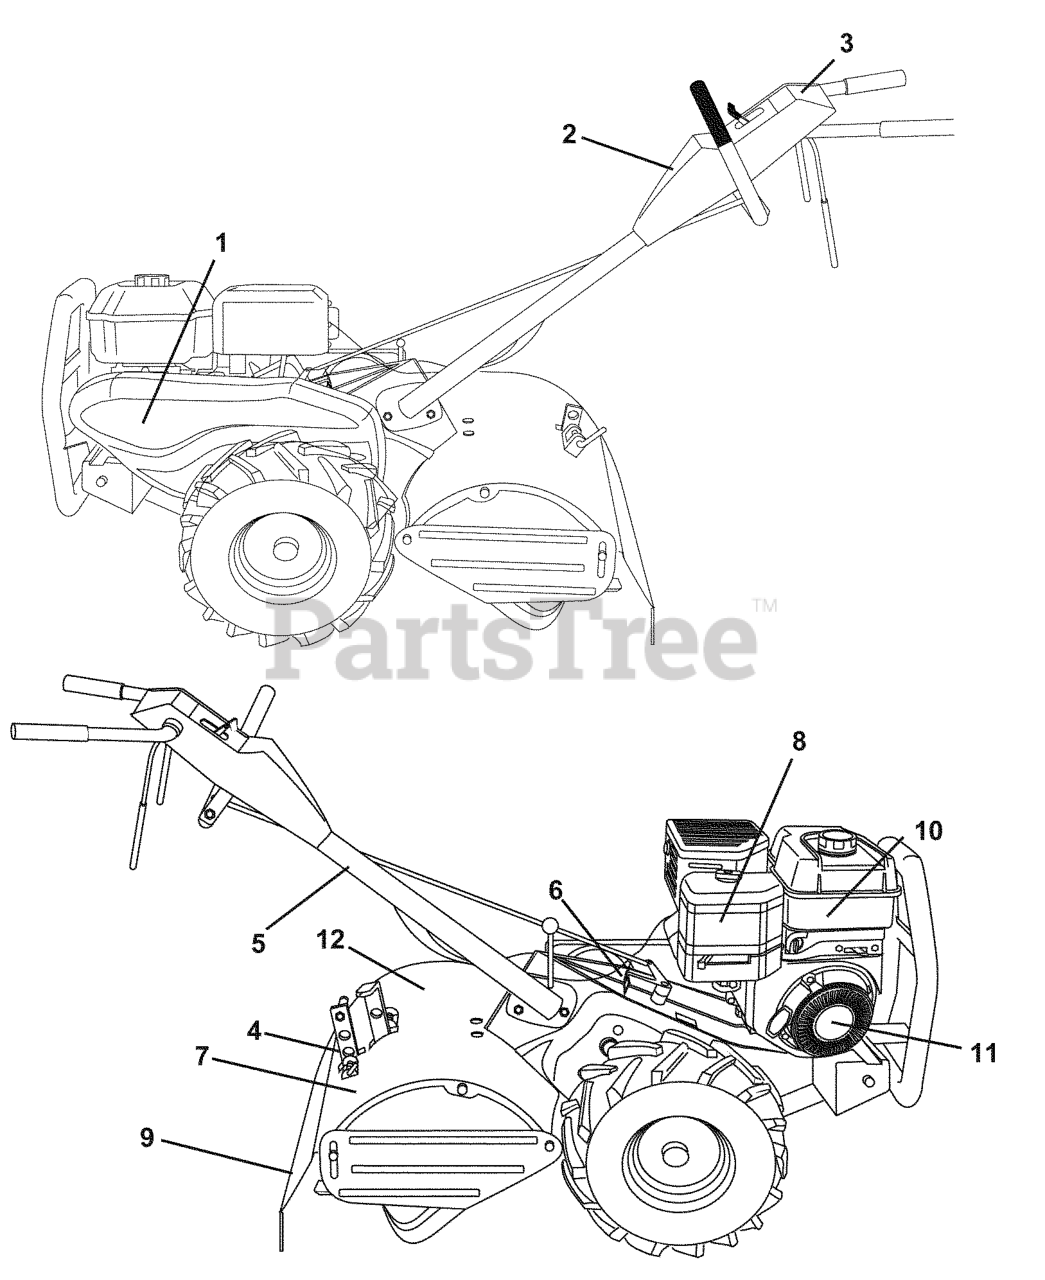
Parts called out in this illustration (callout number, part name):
1	DECAL.HOOD.LOGO.ORANGE.HUSQVAR
2	DECAL.CONSOLE.700DRT.HUSQ
3	DECAL CONSOLE
4	DECAL.SHIELD.TN.DRT17.HUSQ.008
5	DECAL TI (2 2)
6	DECAL.SHIFT.INDICATOR.DRT
7	DECAL.REVERSE.HUSQ
8	DECAL.B&S.900.A/C.REF.277024
9	DECAL.DRT.WARN.ENG/F
10	DECAL.B&S.900.TANK.REF.276991
11	DECAL, REWIND STARTER, B&S
12	DECAL.FORWARD.HUSQ
